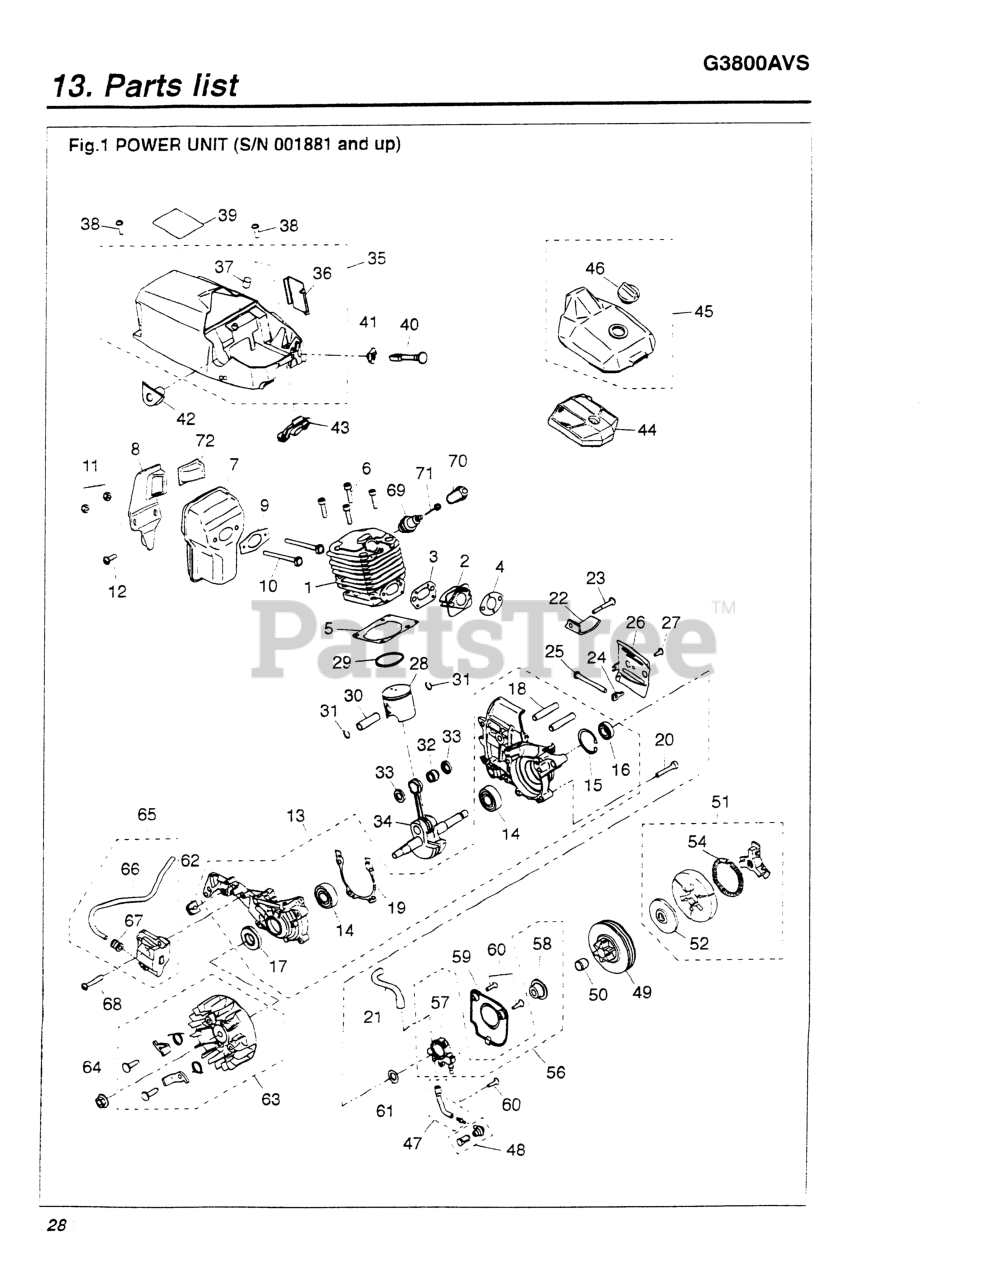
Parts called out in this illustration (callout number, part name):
1	CYLINDER
2	INSULATOR
4	GASKET
5	GASKET, CYLINDER
7	MUFFLER
8	STAY
9	GASKET, MUFFLER
10	BOLT, MUFFLER
11	NUT, MUFFLER (RPLS 3356-15230
12	SCREW (REPLACES 2616-24320)
13	CRANKCASE ASSEMBLY
15	RING, SNAP, M32 x 1.2
16	SEAL, OIL (RPLS 1100-21210)
17	SEAL, OIL
18	STUD (RPLS 0205-50825)
19	GASKET, CASE
20	BOLT
21	PIPE
22	CATCHER, CHAIN (RPLS -25210)
25	SCREW, M5 X 50
26	PLATE (A)
28	PISTON
29	RING, PISTON
30	PIN, PISTON
31	RING, SNAP
32	BEARING
33	WASHER
34	SHAFT COMPLETE
35	COVER COMPLETE
40	ROD, CHOKE
41	GROMMET, CHOKE
42	GROMMET
43	GROMMET, THROTTLE
44	CLEANER, AIR COMP
45	COVER, CLEANER COMP
46	KNOB (RPLS 3356-83322)
47	PIPE
48	FILTER COMPLETE
49	DRUM, CLUTCH
50	BEARING
52	PLATE
54	SPRING
57	PUMP, OIL (USE 848-C40-67A1)
59	COVER, PUMP
60	SCREW
61	WASHER
62	GROMMET
63	ROTOR COMPLETE
65	COIL COMPLETE
66	CORD
67	CAP
68	SCREW
70	CAP
71	SPRING PLUG (RPLS 3310-71320)
72	ARRESTER, SPARK
